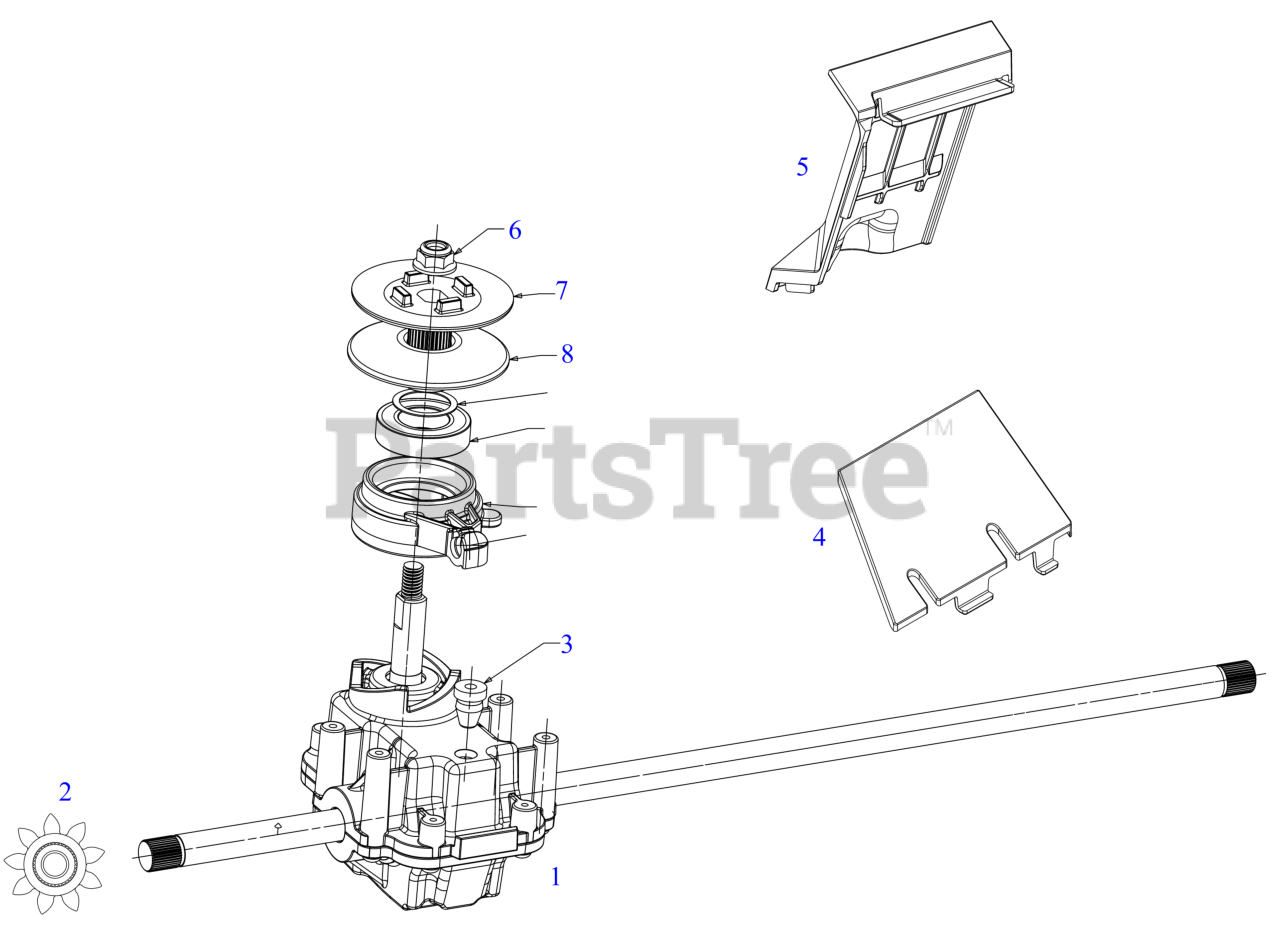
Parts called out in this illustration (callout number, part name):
1	TRANSMISSION
2	SPUR GEAR 9T
3	RUBBER PLUG
4	TRANSMISSION COVER (REAR)
5	TRANSMISSION COVER (REAR)
6	FLANGE LOCK NUT 5/16-18
7	UPPER TRANSMISSION PULLEY
8	LOWER TRANSMISSION PULLEY
